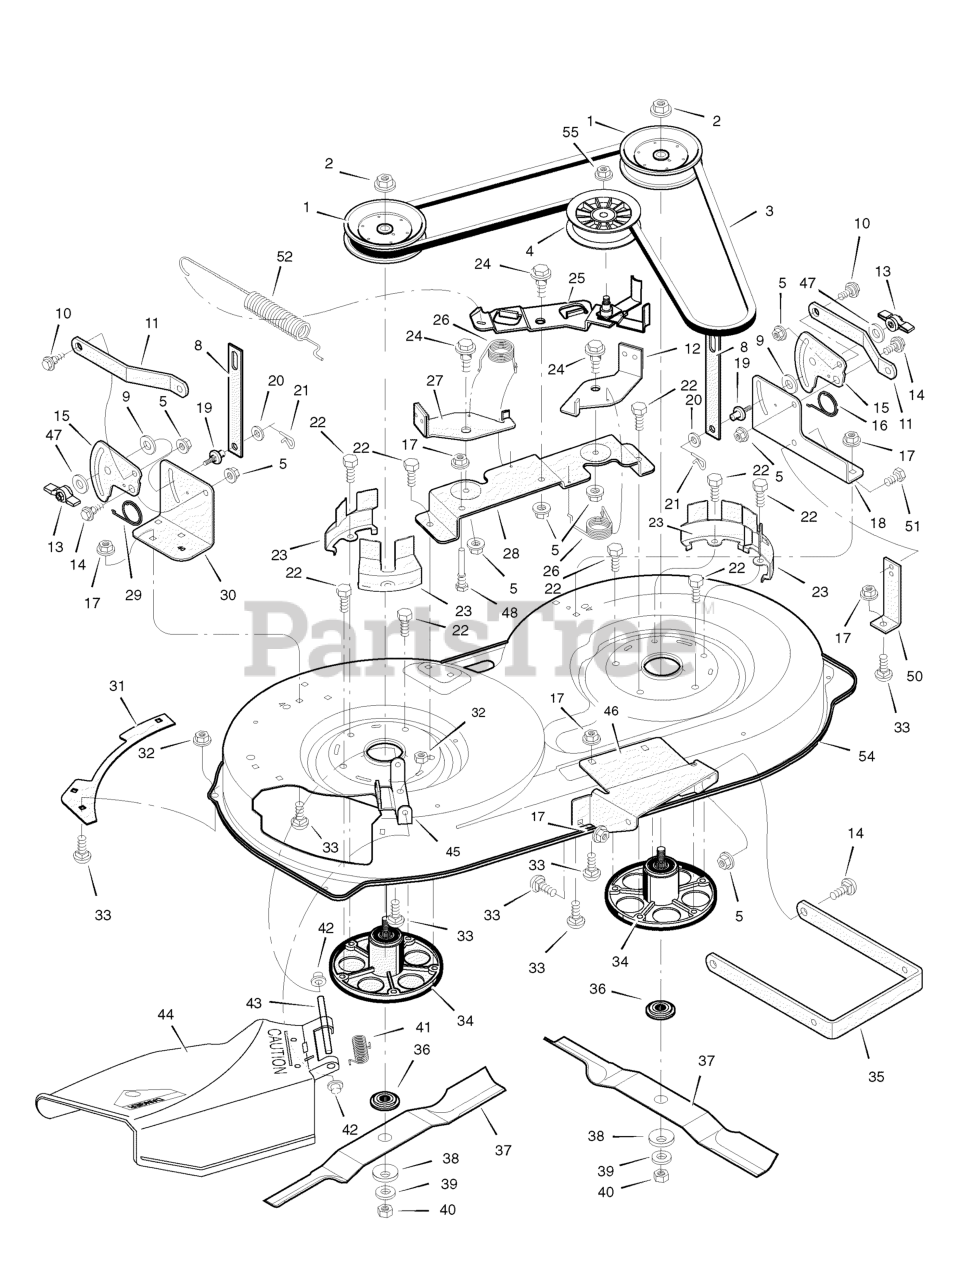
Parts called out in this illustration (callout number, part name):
1	Pulley, Jackshaft
2	Nut, Hex
3	Belt, Mower Drive
4	Pulley, Idler
5	Nut, Flange
8	Link, Lift
9	Pad, Friction
10	Bolt, Shoulder
11	Bracket, Suspension
12	Pad Assembly, Left Brake
13	Knob
14	Bolt, Shoulder
15	Plate, Suspension
17	Nut, Flange
18	Bracket, Left Suspension
19	Pin, Hanger
21	Pin, Cotter
22	Bolt
23	Cover, Pulley
24	Bolt, Shoulder
25	Arm, Idler
27	Pad Assembly, Right Brake
28	Bracket Assembly, Brake
30	Bracket, Right Suspension
32	Nut, Flange
33	Bolt, Carriage
34	Mandrell
35	Bracket, Suspension
36	Adapter, Blade
42	Cap, Push On
43	ROD, Deflector
44	Deflector Assembly
45	Bracket, Deflector
46	Bracket, Front Hanger
48	Guide, Belt
50	Bracket, Support
52	Spring, Extension
54	Housing - Export Blade
55	Nut, Flange
